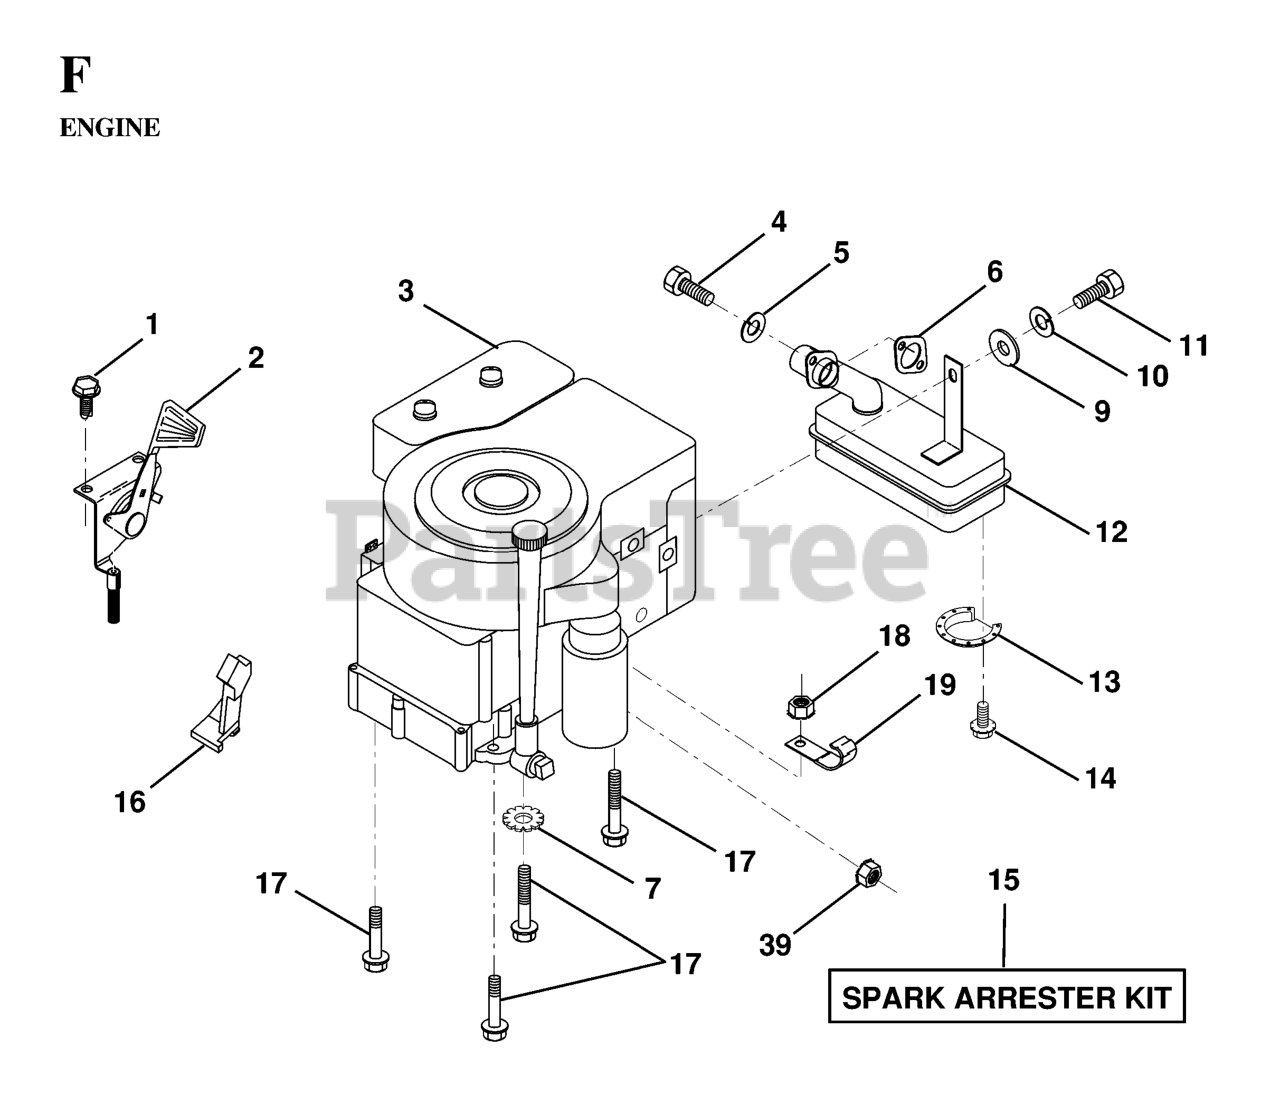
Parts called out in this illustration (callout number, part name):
2	CONTROL.TH/CH.RH.BLK.FLG.EEC
4	SCREW
5	WASHER.LOCK.HVY.HLCL.SPR.5/16
6	GASKET.ENG.1.313 ID.TIN PLATED
7	LOCKWASHER
9	WASHER
10	LOCKWASHER
12	MUFFLER.SINGLE.B&S.12HP
13	DEFL MUFFLER LTV
14	SCREW
15	KIT.SPARK ARRESTOR 794945 B&S
16	STOP THROTTLE
17	SCREW LT
19	CLIP T
39	NUT FLANGE 1/4-20 STARTER NUT
